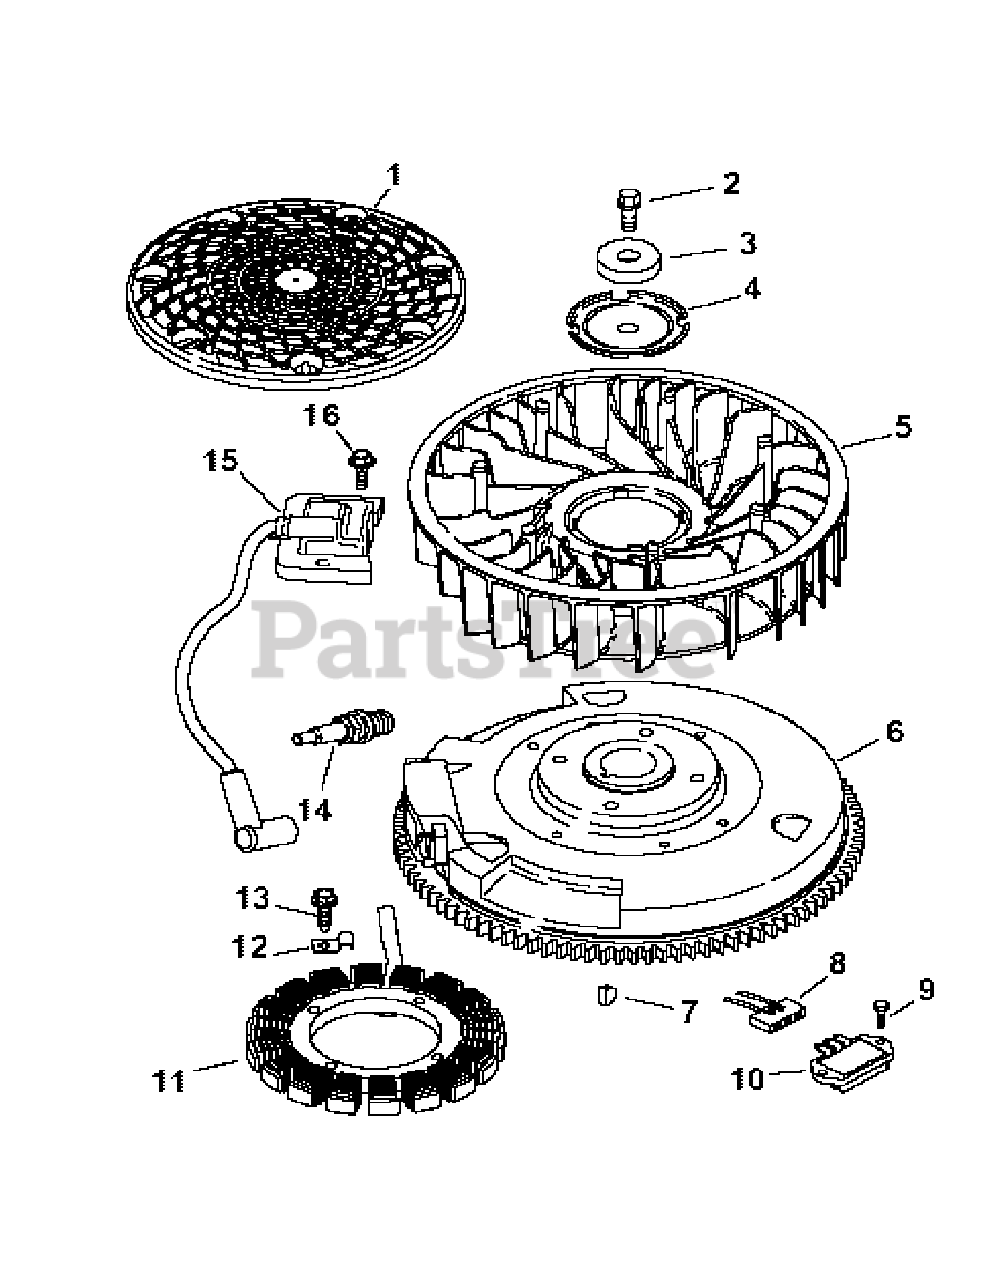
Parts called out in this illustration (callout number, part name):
2	BOLT-HEX
4	Fan Mounting Plate
5	Fan
6	Flywheel
7	Flywheel Key
8	Voltage Regulator
9	Connector
10	Heavy Hex Flange Screw
12	Cable Clip
13	Hex Screw
14	Spark Plug
15	Ignition Module
16	Hex Flange Screw
